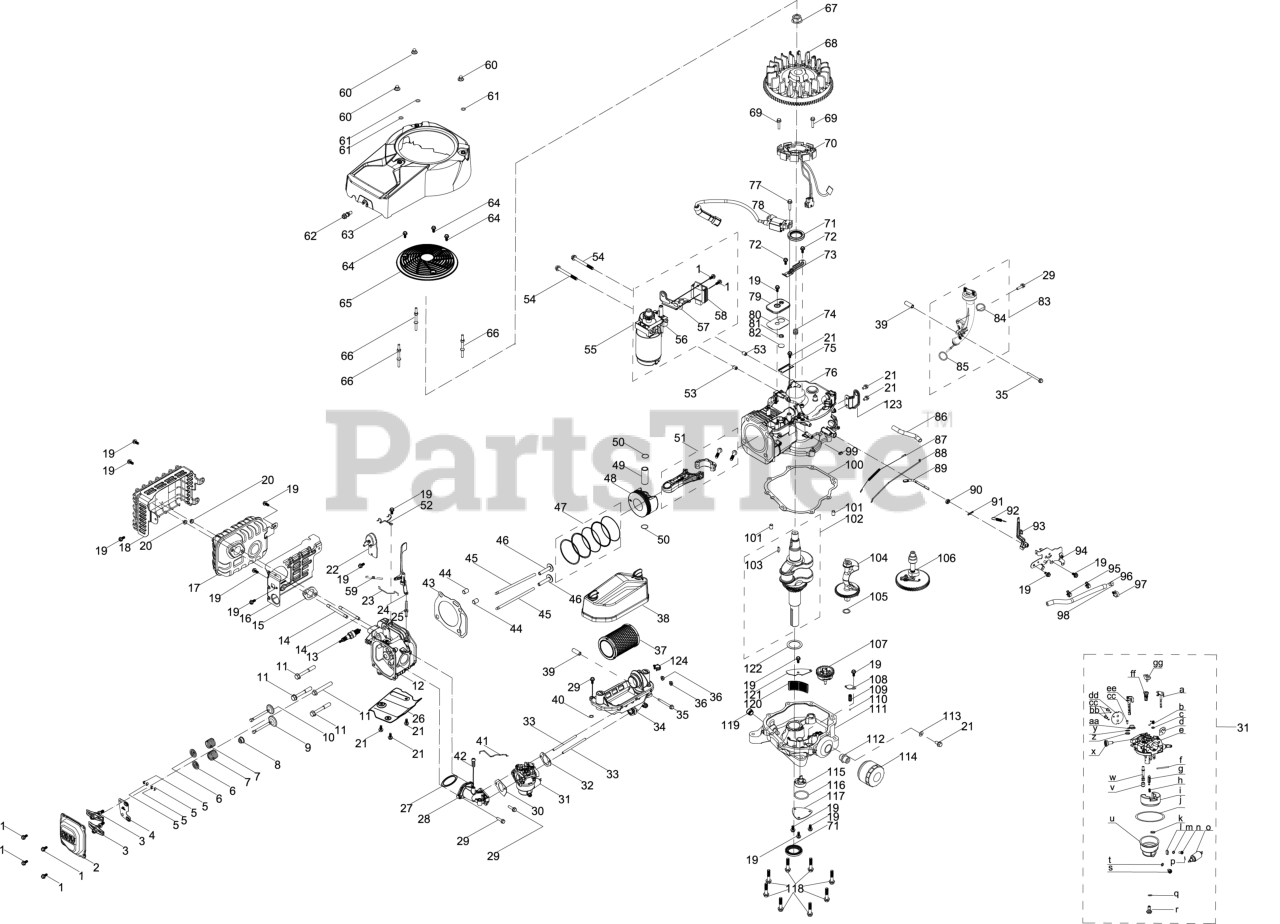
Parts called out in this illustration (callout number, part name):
1	BOLT M6x16
2	VALVE COVER
3	ROCKER ARM ASSEMBLY
4	ROCKER ARM BASE
5	VALVE CAP
6	VALVE SPRING SEAT
7	VALVE SPRING
8	INTAKE VALVE SEAL
9	INTAKE VALVE
10	EXHAUST VALVE
11	BOLT M10x1.25x70
12	CYLINDER HEAD
13	SPARK PLUG (F6RTC/RN11YC/BPR6ES)
14	STUD - M8 x 102
15	EXHAUST GASKET
16	ENGINE SHROUD
18	MUFFLER GUARD
19	BOLT M6x14
21	Bolt, M6×12
22	THERMAL SWITCH
23	THERMAL LEVER
24	AIRVANE CHOKE
25	PIVOT VANE STUD
26	ENGINE SHROUD
27	O-RING 36 x 2.5
28	INTAKE MANIFOLD
29	BOLT M6x22
30	INTAKE GASKET
31	CARBURETOR ASSEMBLY HY-7T84JU
32	AIR FLTER GASKET
33	STUD M6x92
34	AIR FILTER BASE ASSEMBLY
35	BOLT M6x55
37	AIR FILTER W/PREFILTER
38	AIR FILTER COVER ASSEMBLY
39	BUSHING - 11X6X30
40	CARB FUEL DRAIN GASKET
41	CHOKE LEVER
42	SELF TAPPING SCREW 4.8-0.7x16
43	CYLINDER HEAD GASKET
45	PUSH ROD - INDIVIDUAL
47	PISTON RING SET
49	PISTON PIN
50	PISTON PIN SNAP RING
51	CONNECTING ROD ASSEMBLY
54	HEX FLANGE BOLT M8x80
55	Electric Starter
56	ELECTRIC STARTER
59	IDLE SPRING
60	ACORN NUT
63	ENGINE BLOWER HOUSING
64	BOLT M5 x 18
65	ENGINE SHROUD
66	STUD - M6 x 83
67	FLANGE NUT M20-1.5
68	FLYWHEEL ASSEMBLY
69	BOLT M5x28
70	ALTERNATOR
71	OIL SEAL - 35X52X7
72	HEX FLANGE BOLT M5x10
73	WIRE PLATE
75	BREATHER SCREEN
77	BOLT M6x28
78	IGNITION COIL
79	BREATHER COVER
80	BREATHER COVER GASKET
81	BREATHER VALVE SPRING
82	BREATHER VALVE
86	BREATHER HOSE
87	THROTTLE DAMPENING SPRING
88	THROTTLE LINKAGE
89	GOVERNOR GEAR SHAFT
90	GOVERNOR SEAL
91	COTTER PIN
92	GOVERNOR SPRING
93	GOVERNOR ARM ASSEMBLY
94	CONTROL BRACKET ASSEMBLY
95	CARBURETOR HOSE CLAMP
96	FUEL HOSE 6.3x12.5x270
97	FUEL LINE SUPPORT CLAMP
100	CRANKCASE GASKET
101	DOWEL PIN 9 X 14
102	CRANKSHAFT ASSEMBLY
103	WOODRUFF KEY
104	BALANCE SHAFT ASSEMBLY
105	WASHER 17.2 x 26 x 1
106	CAMSHAFT ASSEMBLY
107	GOVERNOR GEAR
108	PRESSURE RELEASE COVER
109	PRESSURE RELEASE SPRING
110	OIL PUMP STEEL BALL
111	CRANKCASE COVER
112	OIL FILTER ADAPTER
113	WASHER - 6.2X1.5X13
114	ENGINE OIL FILTER
115	OIL PUMP ASSEMBLY
117	OIL SEPARATOR
118	BOLT M8 x 40
120	FILTER SCREEN
121	OIL SCREEN PLATE
122	WASHER - 35.4X1X52
